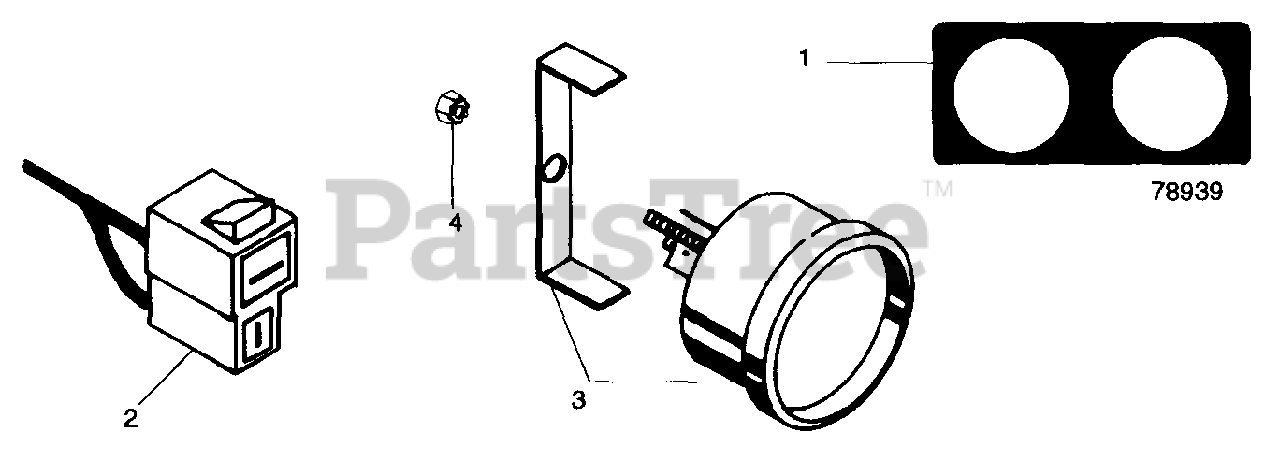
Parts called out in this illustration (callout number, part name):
1	REAR HANGER
1	NUT-LK-JAM-CTR .375-16 PL
1	WSHR-FL-STL .382X.812X.062
1	BLT-SERNK SL .25-20X.50 PL
1	DECAL-PLATE
2	BLT-HEX .38-16X1.00 PL GR5
2	SCR-TAP .375-16X .50 HWH PL TR
2	FAN 16 INCH
2	HARNESS-HOUR METER
3	SPACER .400X.625X.400X.875
3	CHUTE CONTROL CRANK
3	BELT GUARD
3	KEY-WDRF .188X.875X.375 SAE11
3	HOUR METER
4	BLT-HEX .38-16X1.50 PL GR5
4	CHUTE CRANK SUPPORT
4	WSHR-LK .312X.097 PL HVY
4	PIN-ROLL .313X1.75
4	NUT-KEPS 10-24 PL
5	LATCH RH
5	LATCH LH
5	BLT-HEX .31-18X1.50 GR2 YWZC
5	BLT-HEX .31-18X.75 PL GR5
5	WSHR-FL-NYL 1.625X2.500X.060
6	LOCK STOP
6	PIN-HAIR INT .08X.38X1.42 YWZC
6	BLT-HEX .38-16X1.50 PL GR2
7	SPRING WASHER
7	NUT-HEX .250-20 PL
7	WSHR-LK .375X.094 MED PL
7	FRICTION DISC
8	NUT-LK TOP .375-16 GR C YWZC
8	WSHR-LK .313X.062
8	IDLER-V 4.00 X .38 NWHAMSHR
8	DRIVEN PLATE
9	WSHR-LK .375X.115 HVY PL
9	WSHR-FL-STL.281X.62X.065 PL
9	BELT RETAINER
9	BLT-HEX .31-18X2.00 PL GR5
10	NUT-HEX .375-16
10	BLT-RDHDSQNK .25-20X.62 PL
10	PIN-HAIR INT .08X.38X1.42 YWZC
10	PRESSURE PLATE
11	REAR ATTACHMENT BRACE
11	SPOOL
11	SG-COMP .156X.665X.75
12	BLT-HEX .38-16X.75 PL GR5
12	SG-COMP .054X.75X1.6
12	PIN-COTR .09X.75 PL
12	WSHR-FL-STL .323X.625X.062 PL
13	CHANNEL-CROSS
13	NUT-LK DUAL FACE 10-24 PL
13	IDLER BRACKET
13	NUT-LK-TOP .312-18 GR C PL
14	SCR-SKH 10-24X.38
14	KEY-SQ .188X1.0X.188 SAE 8630
14	SG-TENS .187X1.50X9.94 WLD 40
15	NUT .50-13 PL
15	DISC ASSEMBLY
15	PIN-HAIR INT .08X.18X1.18
15	SHFT,WORM
15	JACK PIN
16	ADJUST LINK
16	PIN-ROLL .188X1.00
16	NUT-JAM .75-10 PL
16	ADJUSTMENT PLUG
16	PIN-COTR .12X1.0 PL
17	BLT-HEX .50-13X2.00 PL GR2 FTH
17	WSHR-FL-STL .640X1.005X.062 PL
17	WSHR-LK-INT .750X.050 MED
17	SEAL 1.125X1.375X.125
17	SG-COMP .080X.85X1.44
18	PIN-HAIR INT .09X.188 PL
18	WSHR-FL-STL .781X1.250X.059 PL
18	BRG-CUP1.980X.420
18	BLADE 42 INCH
19	WSHR-FL-STL .390X.750X.125 PL
19	CHUTE CLAMP
19	BRG-BALL .750X1.781X.61
19	BRG-CONE 1.0X.58
19	NUT-HEX .312-18
20	SCR-TAP 10-24X.484 HWH TR
20	SPACER 1.00 X .770/.760 X .813
20	BEARING SPACER 1.032X1.25X1.78
20	WSHR-LK .312X.097 PL HVY
21	BOLT PLATE
21	CABLE CLAMP
21	BSHG, SPCR .755X1.12X.50 PM
21	BLT-RDHDSQNK .31-18X1.00 PL
22	PIVOT ROD
22	SCR-TAP 10-24X.75 HWH PL TR
22	V-BELT, HA-WRAPPED
22	BRG-CONE .750X.61
22	WEAR PLATE
23	NUT-LK-CTR .375-16 GR A PL
23	WSHR-FL-STL .781X1.500X.188
23	BRG-CUP 1.781X.475
23	BLT-RDHDSQNK .38-16X1.0 PL
24	WSHR-FL-STL.656X1.312X.095 PL
24	SCR-MCH 8-32X.75 SLPAN PL
24	V-BELT, HA-COGGED
24	RG-RTNG-INT 1.781X.062
24	SKID SHOE
25	RH LIFT
25	KNOB-BLACK
25	SCR-SET .32-18X.50 SKHCUP OH
25	GEAR CASE - CAST IRON
25	WSHR-FL-STL .438X1.0X.083 PL
26	NUT-JAM .312-18 PL
26	CONTROL CABLE
26	PLY-V 7.50 X .75 W/KEY SALEM
26	SEAL 1.625X2.125X.250
26	WSHR-LK .375X.094 MED PL
27	WSHR-LK .313X.078 PL MED
27	PIN-COTR .09X.75 PL
27	NUT-LK-CTR .250-20 PL
27	PIPE PLUG
28	SPRING BRACKET RH
28	CHUTE DEFLECTOR
28	BEARING FLANGE
28	WSHR-FL-STL .328X1.0X.094
28	PIN-COTR .18X1.0 PL
29	PIN,THREADED
29	BLT-HEX .38-16X.75 PL GR2
29	BRG-BALL1.0X2.0X.56
29	WSHR-LK .312X.097 PL HVY
29	SUPPORT
30	SG- GAS COMP .31X.75X10.00
30	DISCHARGE CHUTE
30	BEARING FLANGE
30	BLT-HEX .31-18X.75 PL GR2
31	RG-RTNG-EXT .312 X .020
31	40 AUGER/16 IMPELLER HOUSING
31	BLT-RDHDSQNK .38-16X1.50 PL
31	DUST CAP
31	WSHR-FL-STL.656X1.312X.095 PL
32	BLT-HEX .38-16X2.00 PL GR2
32	BLT-RDHDSQNK .31-18X.75 SHT PL
32	SG-TENS .090X.75X3.50 WLD 34
32	WORM & GEAR SERVICE ASSEMBLY
32	LIFT LINK
33	WSHR-FL-STL .406X1.125X.125 PL
33	BLT-RDHDSQNK .38-16X.75 SHT PL
33	IDLER ARM
33	KEY-FTHR .25X.875X.25 SAE 8630
33	PIN-HAIR EXT .12X.31X2.37 PL
34	BLT-RDHDSQSHNK .38-16X1.00 PL
34	BSHG-FLG .372X.500X.312X.625NY
34	BSHG-FLG .683X1.87X1.68X2.250
34	PIVOT ROD
35	SCRAPPER BLADE
35	PIN-COTR .12X.75 PL
35	WSHR-FL-STL 1.625X2.500X.012
35	FRAME HTH BLADE
36	NUT-LK TOP .375-16 GR C YWZC
36	WSHR-FL-STL .505X.880X.072 PL
36	BSHG-SLV 1.125X1.250X1.000
37	SCRAPER BLADE BRACE
37	SPACER -FLANGED .390X.500X.781
37	KEY-SQ .25X.625X.375
37	WSHR-FL-STL .390X.750X.125 PL
38	BLT-HEX .38-16X.75 PL GR5
38	IDLER
38	GEAR CASE SHAFT
38	PIN-HAIR INT .09X.188 PL
39	WSHR-FL-STL .38X.875X.083 PL
39	NUT-LK-CTR .375-16 GR A PL
39	SPACER .406X.749X.162
40	NUT-LK .312-18 GR A PL
40	GEAR CASE COVER
40	BLT-HEX .31-18X1.25 PL GR2
41	RUNNER-SKID SHOE
41	40 INCH RAKE SHAFT
41	LATCH PIN
42	NUT-FLG. .312-18 PL
42	ARIENS 16 OZ.BOTTLE OF L2 LUBE
42	BLT-RDHDSQNK .31-18X.75 SHT PL
43	BLT-HEX .25-20X.75 PL GR2
44	WSHR-LK-EXT. 250 ID
44	NUT-LK .312-18 GR A PL
45	SPIN DRIVE ZERK FITTING
45	PIN-COTR .12X.75 PL
46	NUT-LK .312-18 GR A PL
47	RAKE, LEFT-40"(1.12ID X 15.75)
47	UNIVERSAL BLOCK JOINT
48	WSHR-LK .500X.151 HVY PL
49	BLT-HEX .50-13X1.00 PL GR2
49	CHUTE CRANK SUPPORT
50	WSHR-FL-STL .511X1.441X.125 PL
51	BSHG-FLG 1.000X1.12X.62X1.50BR
51	PIVOT PLATE
52	NUT-LK-FLG .250-20 PL
52	BLT-HEX .31-18X1.50 GR2 YWZC
53	BEARING SUPPORT
53	NUT-FLG. .312-18 PL
54	GEAR CASE -16" IMPELLER - C.I.
